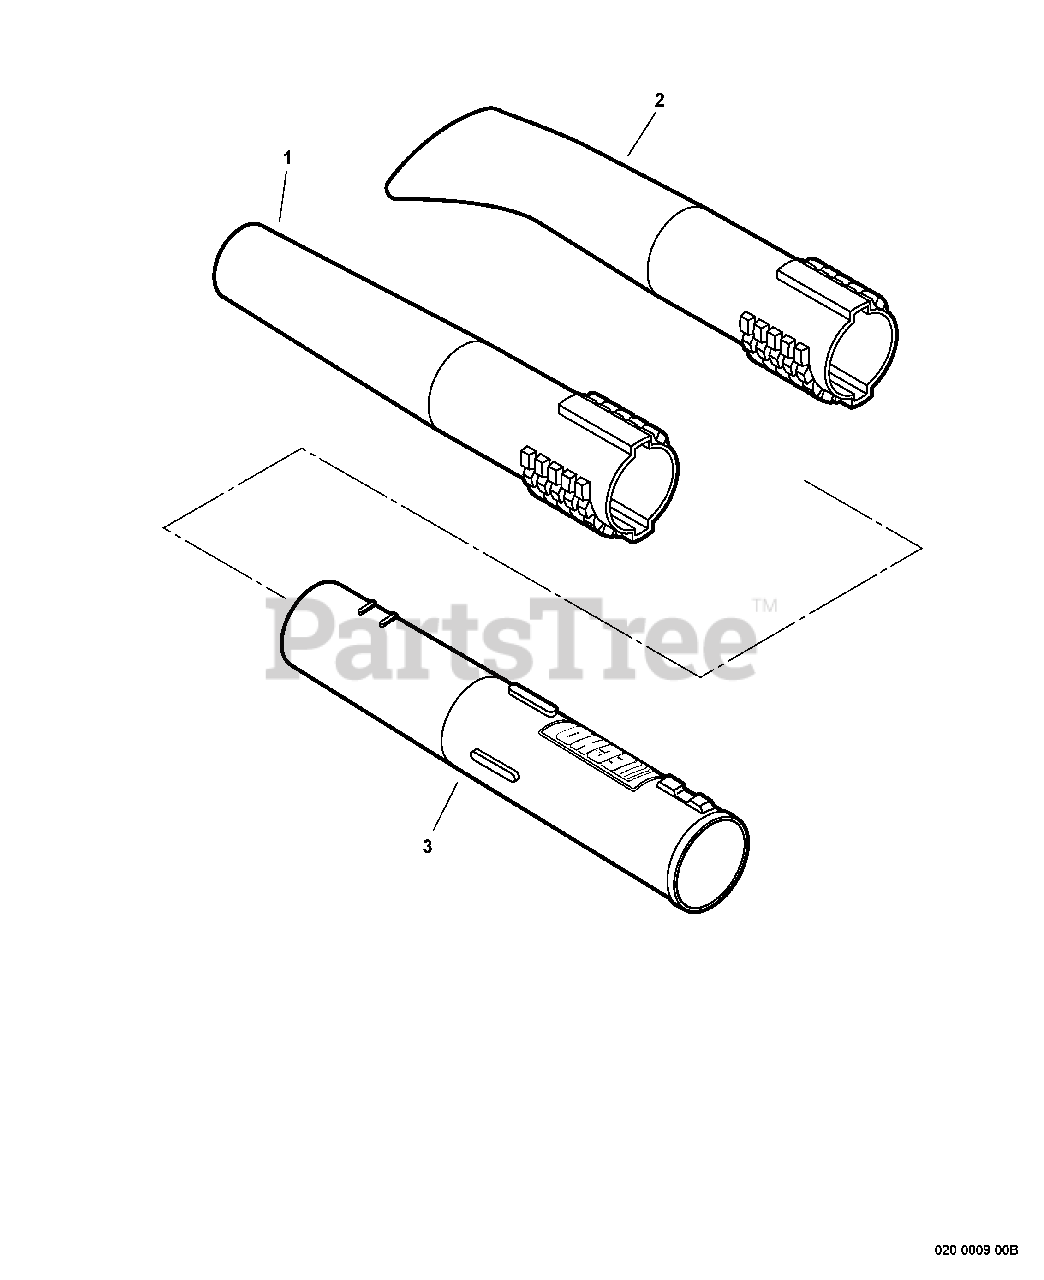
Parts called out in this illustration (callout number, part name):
1	TUBE, BLOWER - STRAIGHT NOZZLE
2	TUBE, BLOWER - CURVED NOZZLE
3	TUBE, BLOWER - STRAIGHT
